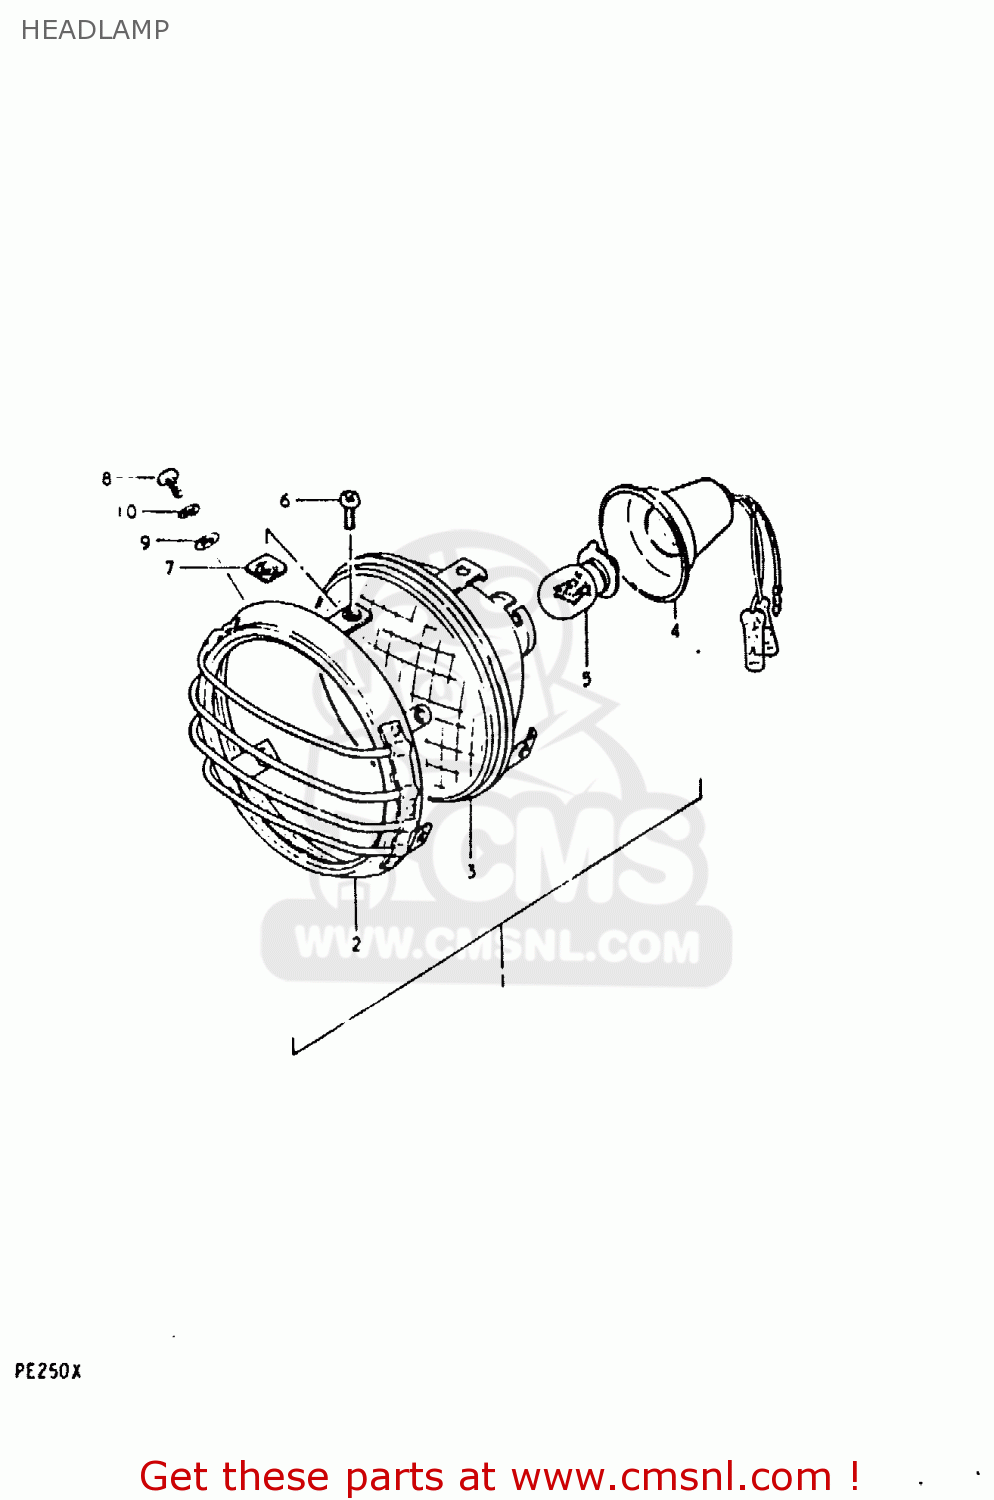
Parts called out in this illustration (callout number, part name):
1	HEADLAMP ASSEMBLY
2	RIM,HEADLAMP
3	LAMP UNIT
4	SOCKET,HEADLAMP
5	BULB(6V15/15W/STANLEY,A3598HA)
6	SCREW
7	NUT
8	SCREW
9	WASHER
10	LOCK WASHER
